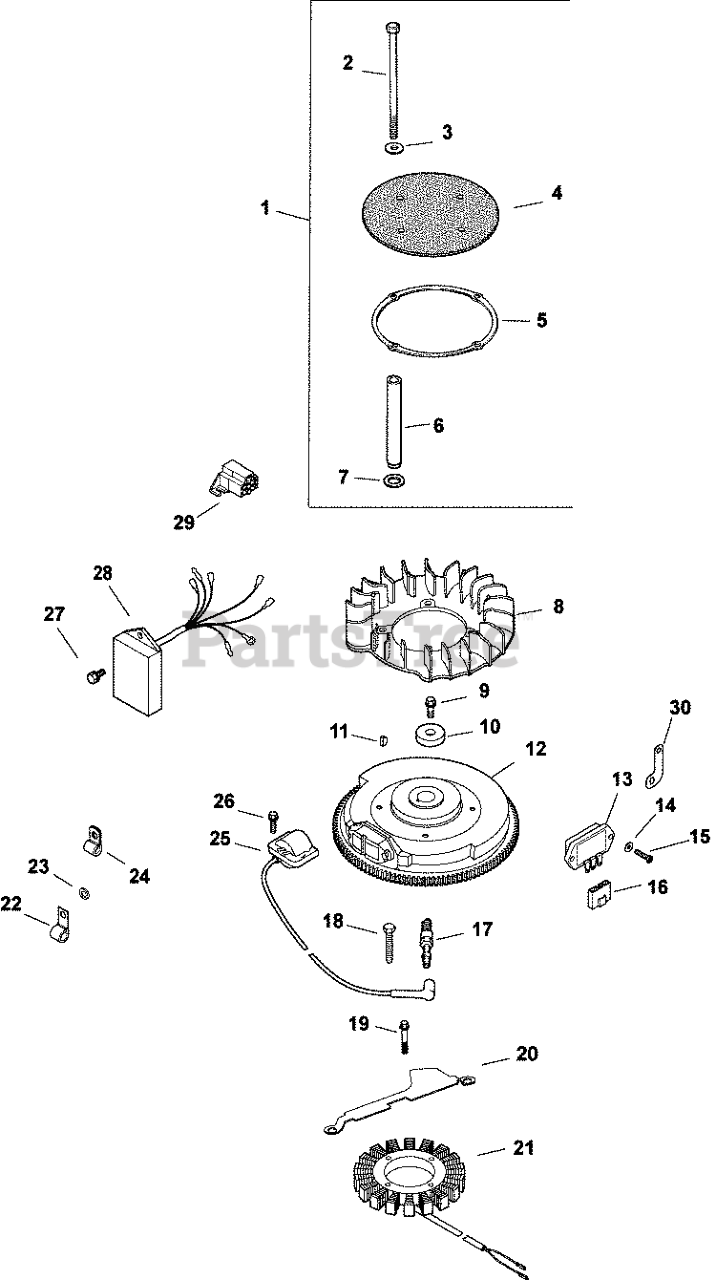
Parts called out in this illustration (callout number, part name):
1	KIT, CHOPPER SCREEN
2	SCREW, CAP M6X1.0X99.5
3	WASHER, FLAT 1/4" (O.D. 5/8")
4	SCREEN, GRASS
5	RING, SUPPORT USE 25 141 08-S
7	WASHER, SPRING 10 MM
8	FAN (DOMED)-USE 24 157 17-S
9	SCREW, FLG M10X1.5X45 - (#25086361S)
10	WASHER, FLAT 13/32"
11	KEY, 3/16" X 5/8"
12	FLYWHEEL, PAINTED-USE 24 025 57-S
13	REG/RECT-15 AMP (KM)-USE 41 403 10-S
14	WASHER, FLAT 3/16"
15	SCREW, PHL HD #11-16X7/8"
16	CONNECTOR, BODY (KM)-USE 25 155 41-S
17	PLUG, SPARK (STD)
18	SCREW, M5X0.8X25 - (#25086402S)
19	SCREW, SKT SET #10-24X1/4"
20	BRACKET, STATOR WIRE
21	KIT, 15 / 20 AMP STATOR
22	CLIP, CABLE
23	WASHER, FLAT 1/4" (O.D. 1/2")
25	MODULE USE 24 584 36-S
26	SCREW, SKT THD FRM M5X0.8X25
27	SCREW, THD FRM M4X0.7X10
28	MODULE, SPEED ADVANCE-DISCONTINUED SEE PB265
29	CONNECTOR
30	BRACKET, GROUND STRAP USE 24 518 12-S
